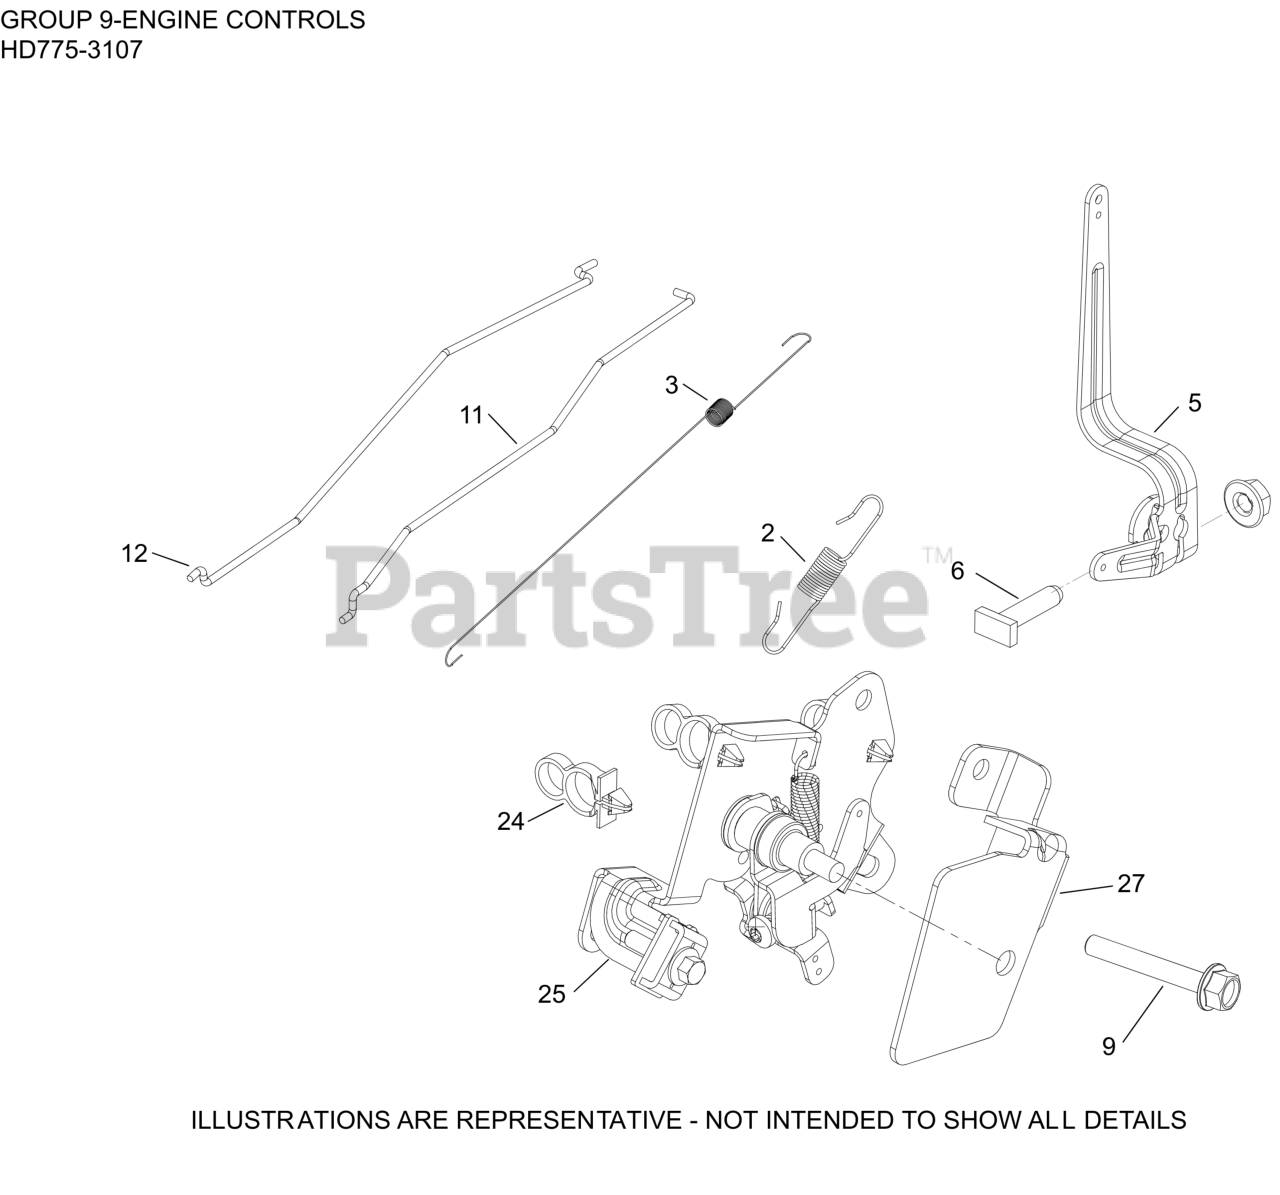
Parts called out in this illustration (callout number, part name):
2	SPRING, GOV (2800-3300 RPM)
3	SPRING, LINKAGE
5	LEVER, GOVERNOR
6	SCREW, RECTANGLE HEAD (M6)
9	SCREW, HEX FLANGE (M6)
11	LINKAGE, GOVERNOR
12	LINKAGE, CHOKE
24	CLIP, FUEL LINE
25	CONTROL ASSY, VARIABLE SPEED NO-KILL
27	GUARD, SPEED CONTROL ASSEMBLY
